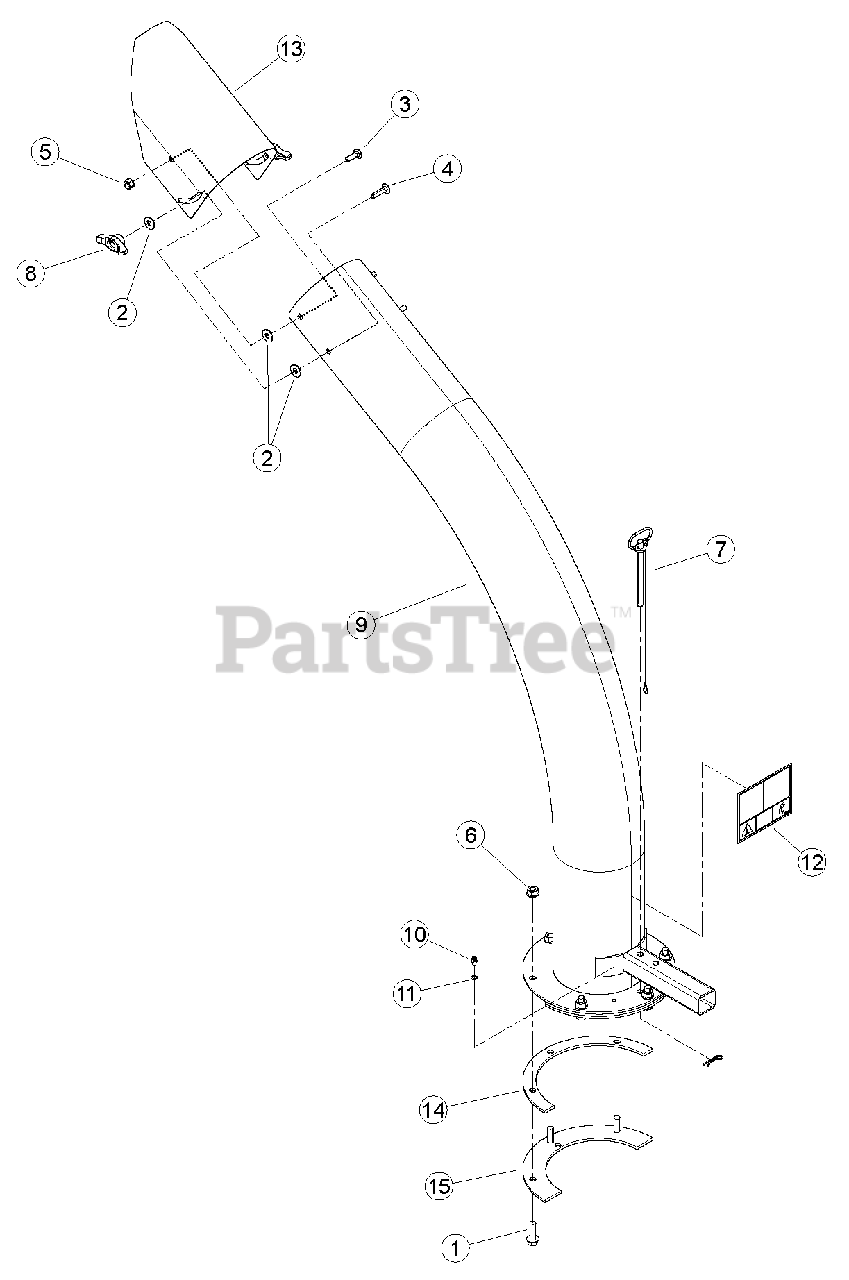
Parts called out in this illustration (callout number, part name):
1	BOLT, 3/8 X 1-1/4 FLANGE NC
2	WASHER, 5/16" FLAT ZP
3	BOLT, 5/16 X 1" GR5 CRG ZP
4	BOLT, 5/16 X 1-1/4" GR5 CRG ZP
5	NUT, 5/16-18 NYLOCK-FLANGE
6	NUT, 3/8-16 NYLOCK FLANGE
7	PIN, 3/8 X 4.25" DISCHARGE
8	KNOB, 5/16-18 UNC TEE W/ LOCKING INSERT
9	ASSEMBLY, 6 INCH DISCHARGE CHUTE
10	FITTING, 1/4 SELF-TAP GREASE
11	WASHER, FLAT .254 X .400 X .048
12	DECAL, DISCHARGE DEBRIS & LOCK
13	DEFLECTOR, BLOWER VAC DISCHARGE
14	SPACER, DISCHARGE PIVOT
15	RING, DISCHARGE CLAMP
